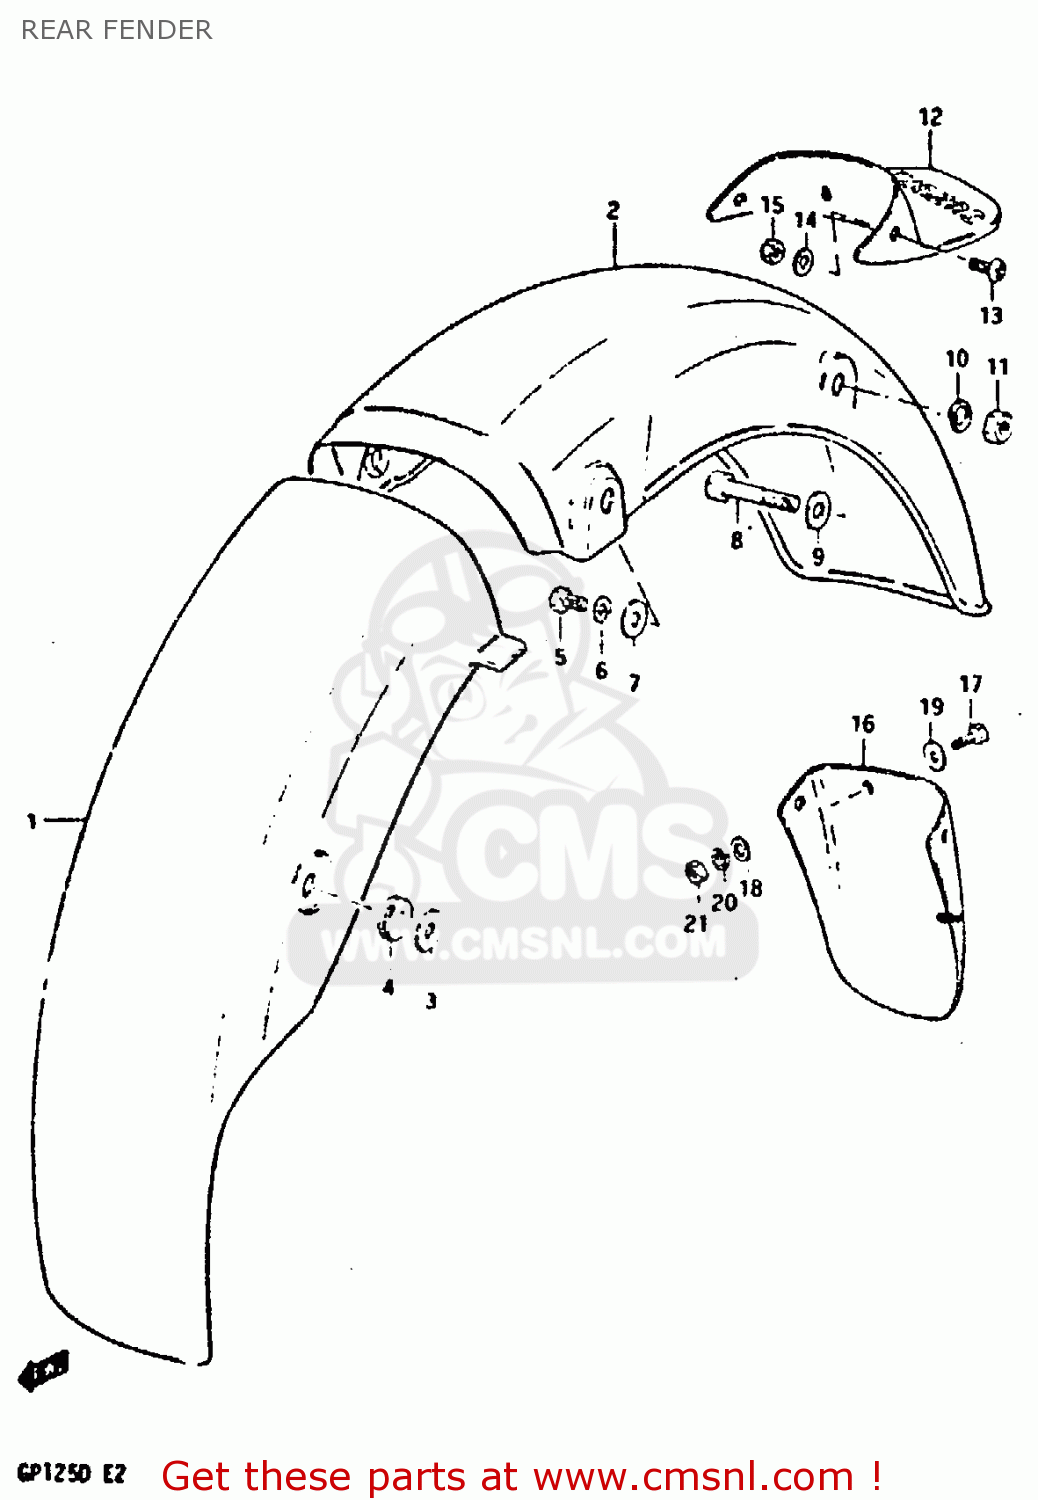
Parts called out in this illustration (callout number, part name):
1	BODY,RR FENDER FR
2	BODY,RR FENDER RR
3	WASHER
4	CUSHION
5	BOLT
6	LOCK WASHER
7	WASHER
8	BOLT 8X45
9	WASHER
10	LOCK WASHER
11	NUT
12	EXTENSION,RR FENDER
13	SCREW
14	WASHER
15	NUT
